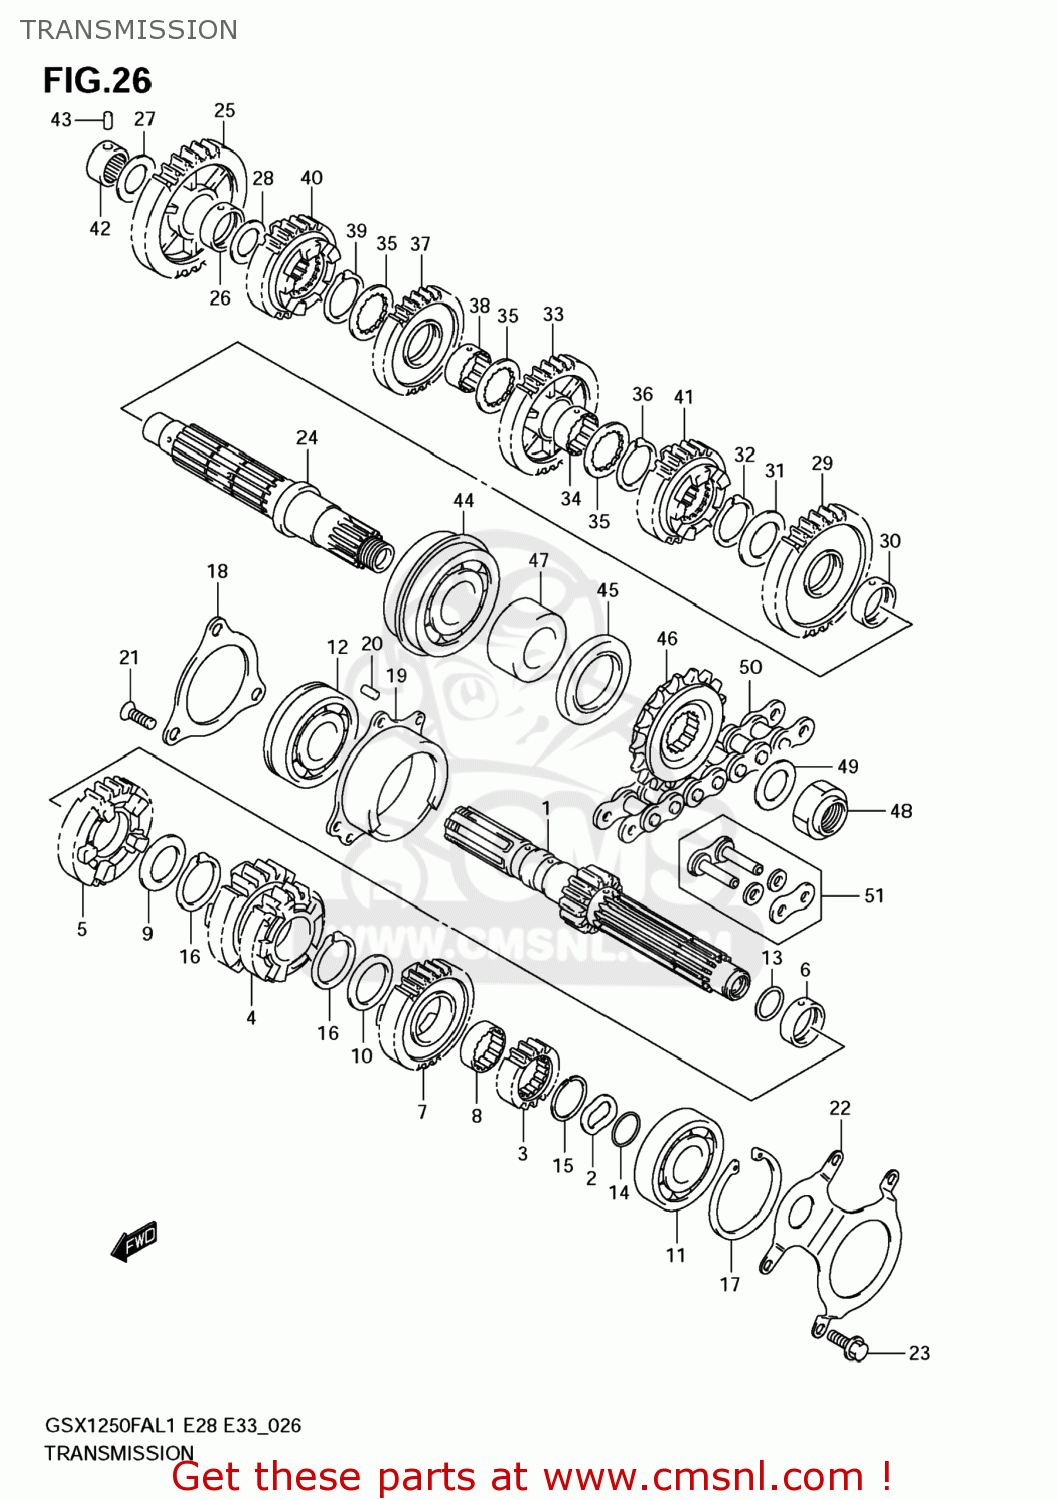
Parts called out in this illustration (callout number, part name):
1	SHAFT,COUNTER
2	WASHER,COUNTER SHAFT WAVE
3	GEAR,2ND DRIVE
4	GEAR,3RD & 4TH DRIVE(NT:20/23)
5	GEAR,5TH DRIVE(NT:25)
6	BUSH,5TH DRIVE GEAR
7	GEAR,6TH DRIVE(NT:28)
8	BUSH,6TH DRIVE GEAR
9	WASHER(27X36X1)
10	WASHER,LOCK
11	BEARING(20X52X15)
12	BEARING(25X62X17)
13	O RING(D:1.9,ID:16.6)
14	O RING(D:1,ID:19.5)
15	CIRCLIP
16	CIRCLIP
17	CIRCLIP
18	RETAINER,CNTR SHAFT BEARING,R
19	HOUSING,CNTR SHAFT BRG,R
20	PIN
21	SCREW(6X20)
22	RETAINER,CL PUSH ROD OIL SEAL
23	BOLT(6X12)
24	SHAFT,DRIVE
25	GEAR,1ST DRIVEN(NT:40)
26	BUSH
27	SHIM(20X34X1)
28	SHIM(22X34X1)
29	GEAR,2ND DRIVEN(NT:35)
30	BUSH,2ND DRIVEN GEAR
31	WASHER(27X36X1)
32	CIRCLIP
33	GEAR,3RD DRIVEN(NT:31)
34	BUSH,3RD DRIVEN GEAR
35	WASHER,3RD & 4TH DRIVEN
36	CIRCLIP
37	GEAR,4TH DRIVEN(NT:30)
38	BUSH,3RD DRIVEN GEAR
39	CIRCLIP
40	GEAR,5TH DRIVEN(NT:29)
41	GEAR,6TH DRIVEN(NT:30)
42	BEARING(20X34X13.5)
43	PIN(6X10)
44	BEARING(30X62X23.8)
45	SEAL,OIL(42X62X7)
46	SPROCKET,ENGINE(NT:18)
47	SPACER,ENGINE SPROCKET
48	NUT
49	WASHER(25X40X1.4)
50	CHAIN,DRIVE(RK50GSVZ3M)
51	JOINT SET
